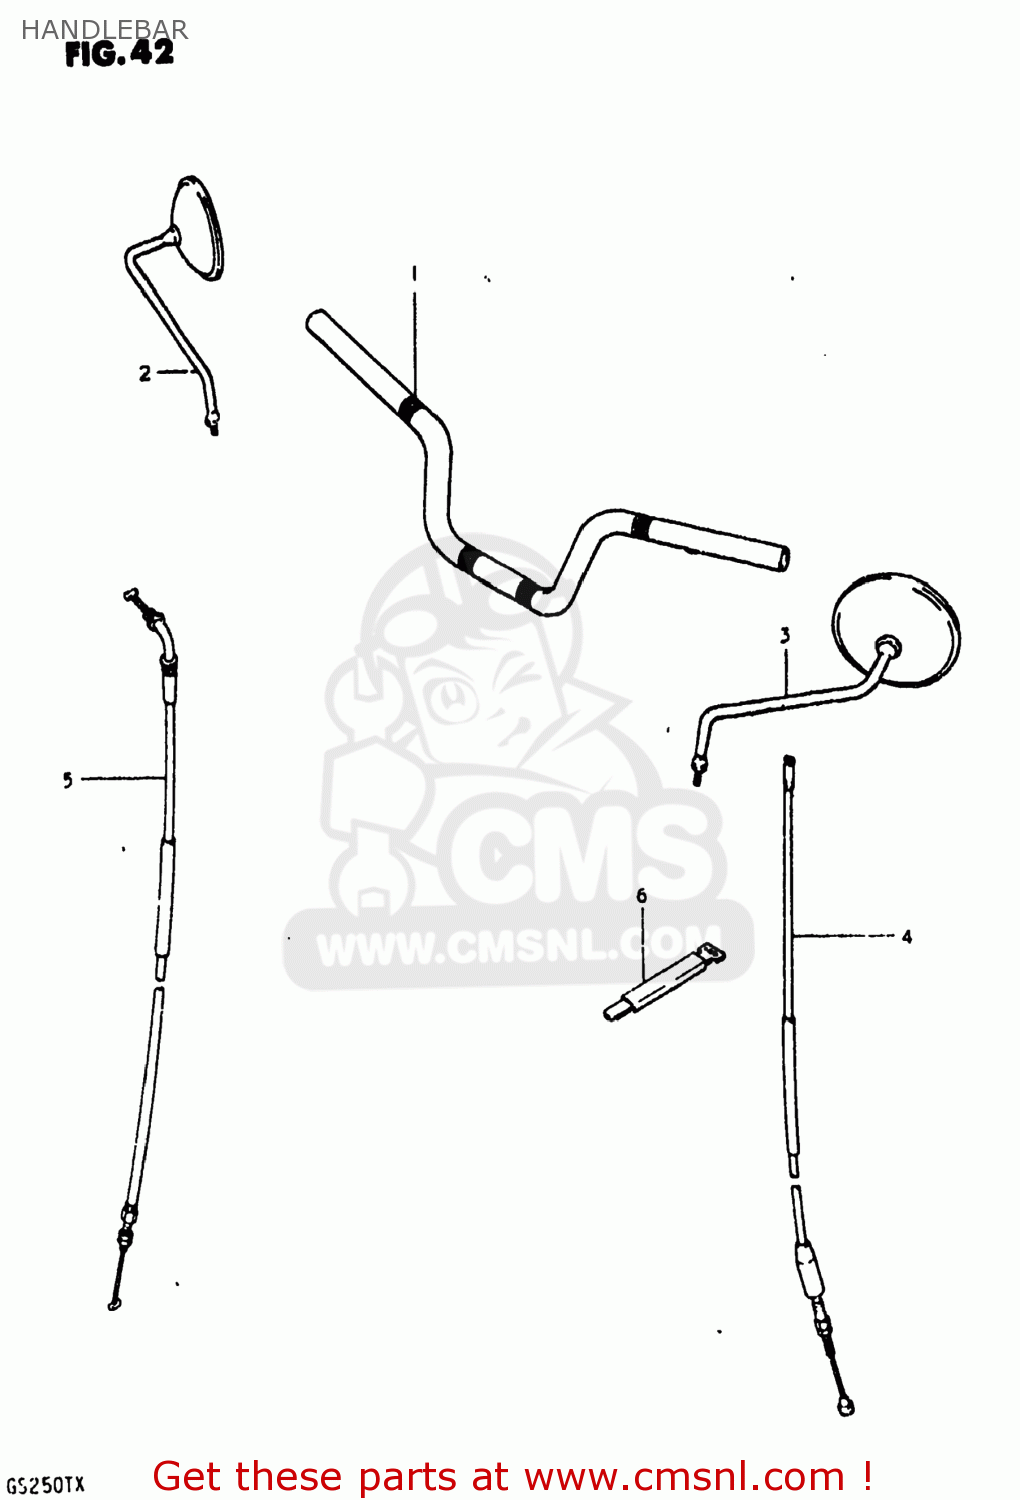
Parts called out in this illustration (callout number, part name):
1	HANDLEBAR
2	MIRROR ASSEMBLY,RIGHT
3	MIRROR ASSEMBLY,LEFT
4	CABLE ASSEMBLY,CLUTCH
5	CABLE ASSEMBLY,THROTTLE
6	CLAMP
